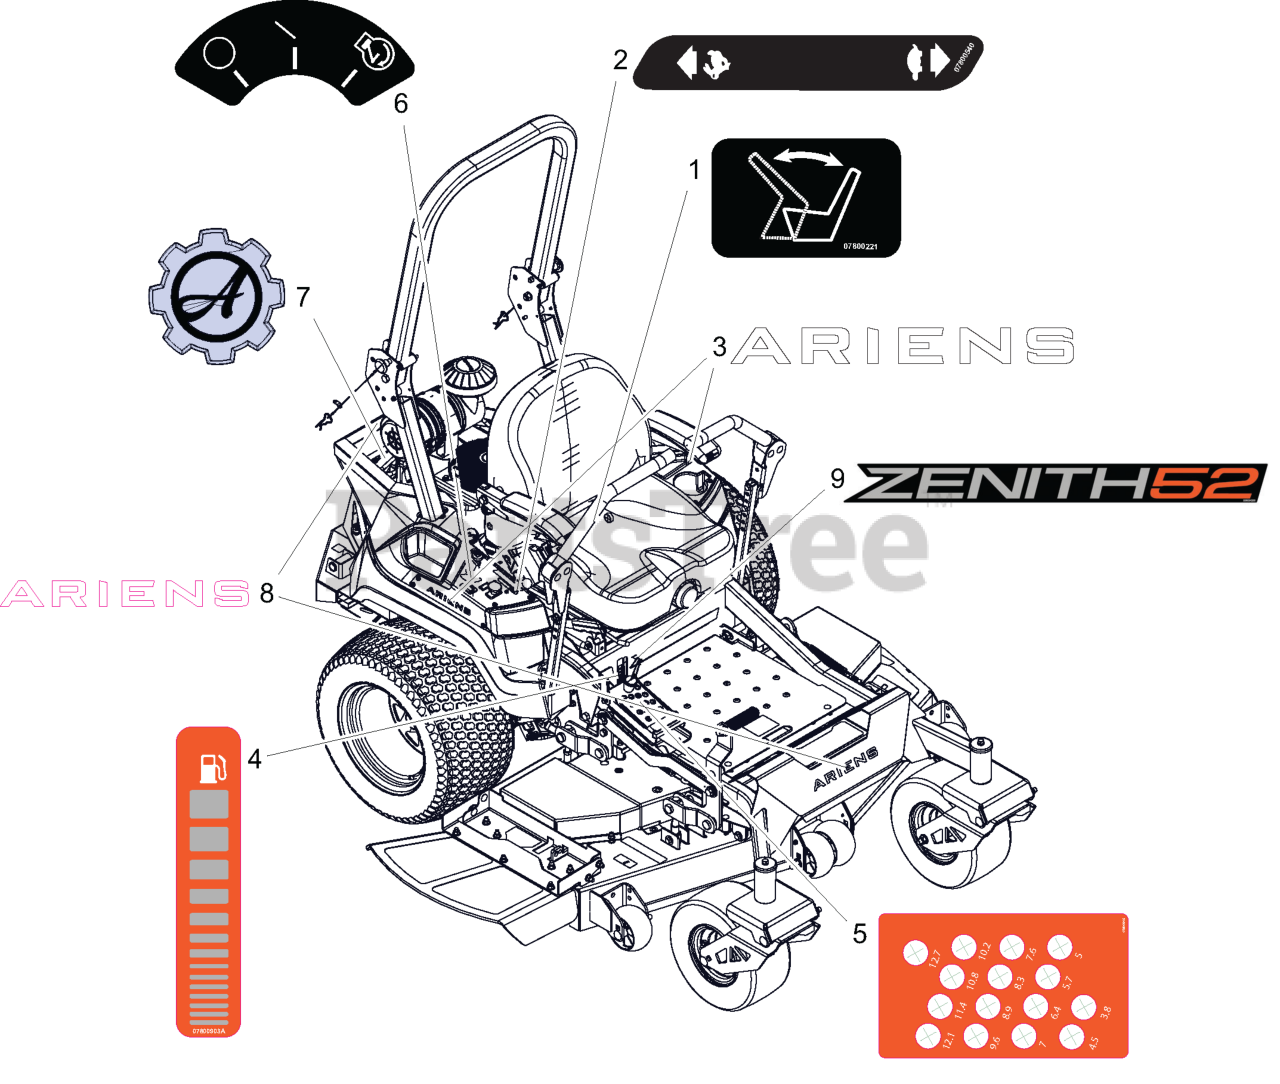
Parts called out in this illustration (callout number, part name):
1	DECAL - SEAT RELEASE
2	DECAL, DASH DECAL
3	DECAL, ARIENS (6.50")
4	DECAL, ARIENS FUEL LEVEL
5	DECAL, APEX HOC METRIC
6	DECAL, KEYSWITCH
7	DECAL- ARIENS GEAR BADGE
8	DECAL - ARIENS 9.625"
9	DECAL, ZENITH 52
